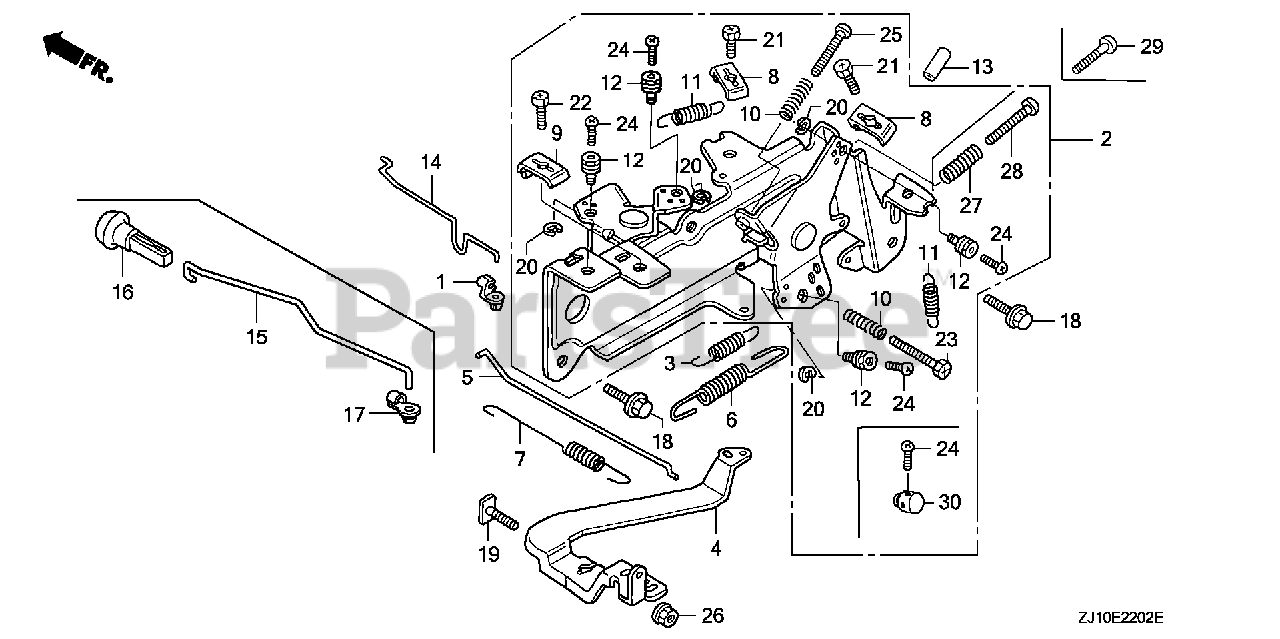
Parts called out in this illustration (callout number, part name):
1	JOINT, ROD
2	CONTROL ASSY.
3	SPRING, STARTER
4	ARM, GOVERNOR
5	ROD, GOVERNOR
6	SPRING, GOVERNOR
7	SPRING, THROTTLE RETURN
9	HOLDER, CABLE
10	SPRING, CONTROL ADJUSTING
11	SPRING, CABLE RETURN
14	ROD, CHOKE CONTROL
18	BOLT, FLANGE (6X14) (CT200)
19	BOLT, GOVERNOR ARM
22	BOLT, RECESSED (5X16)
23	BOLT, RECESSED (5X25)
25	SCREW, PAN (5X25)
26	NUT, FLANGE (6MM)
